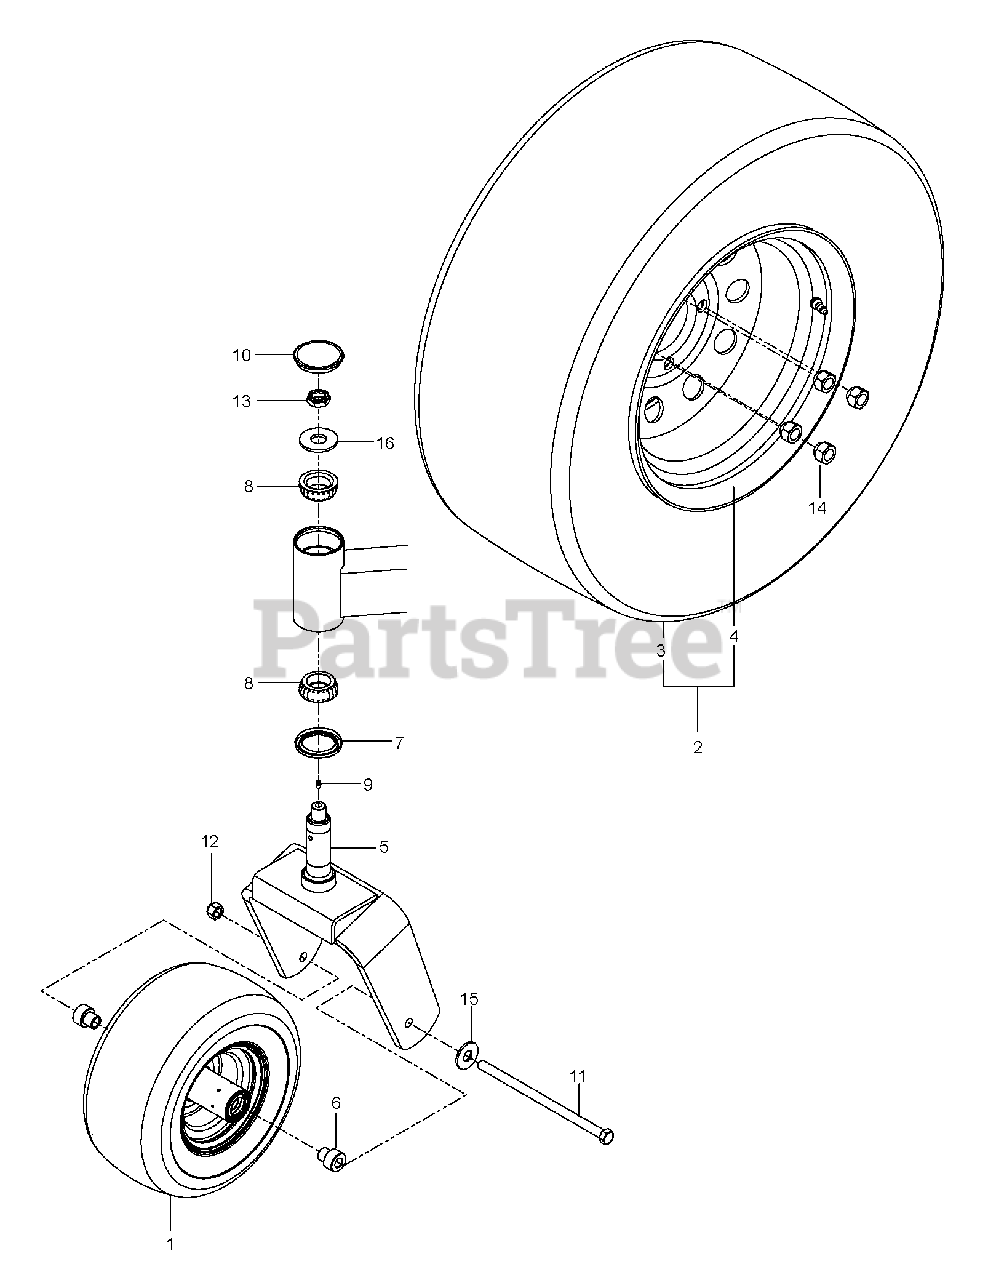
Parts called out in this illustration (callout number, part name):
1	TIRE, 13 X 6.5-6 NO FLAT
2	WHEEL/TIRE.ASM.24X12-12.SILVER
3	TIRE.24X12-12.TURF.MASTER
4	RIM, 12 X 8.5 W/1.75 NEG OS
5	FORK.CASTER.ORANGE
6	AXLE SPACER
7	SEAL, BEARING
8	CONE, LM67048
11	HEX SCREW 1/2-13 X 9.5 GR5
12	NUT, 1/2-13 HEX FLG NYLOC ZD
13	NUT, 3/4-16 HEX THIN NYLOC ZD
14	LUG NUT 1/2F
15	WASHER 1/2" FLAT
16	WASHER, 3/4 HARDENED
